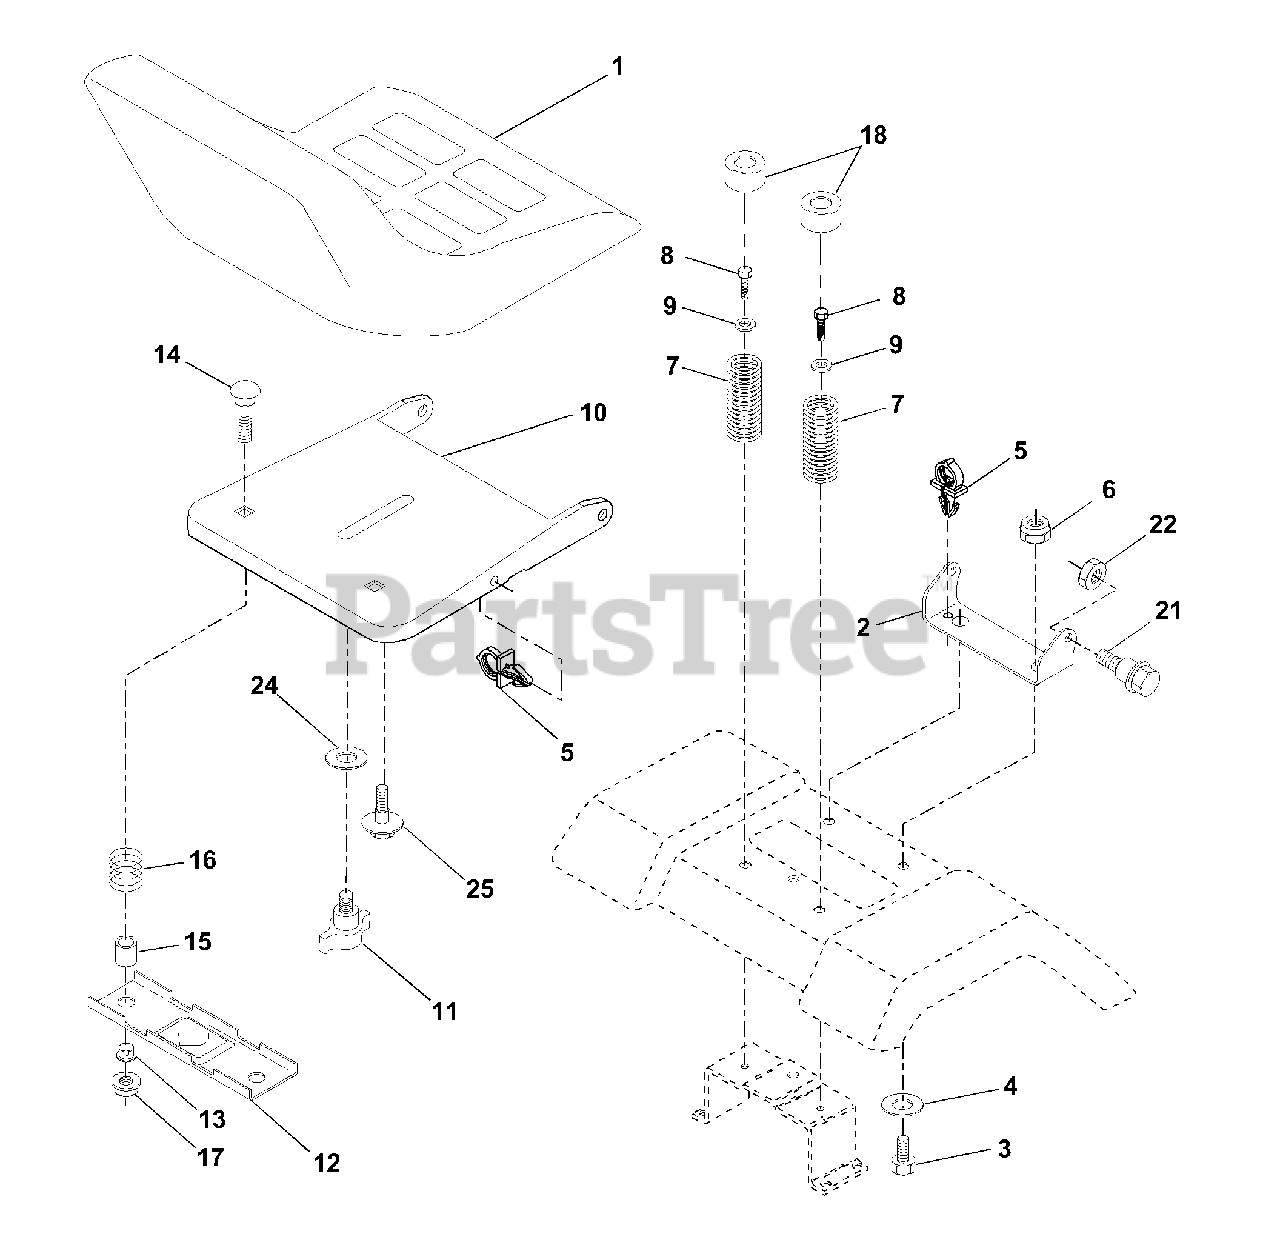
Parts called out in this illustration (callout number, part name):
1	Seat
2	Bracket Pivot Seat 8 720
3	Bolt Fin Hex 3/8-16unc X 1
4	Washer 13/32 X 1 X 10 Ga
5	Clip Push-In
6	Nut Hex w/Ins. 3/8-16 Unc
7	Spring Seat Cprsn 2 250 Blk Zi
8	Screw Thdrol 3/8-16 X 1-1/2
9	Washer 13/32 X 1 X 14 Ga.
10	Pan Seat
11	Knob Seat Adj Wingnut
12	Bracket Mounting Switch
13	Bushing Snap Blk Nyl 50 Id
14	Bolt Rdhd Sqnk 1/4-20x1-1/2
15	Spacer Split 28x 96 Yel Zinc
16	Spring Cprsn 1 27 Blk Pnt
17	Nut Lock 1/4 Lge Flg Gr 5 Zinc
18	Cap Spring Seat
21	Bolt Shoulder 5/16-18 Unc
22	Nut Hex Lock W/Ins 5/16-18
24	Washer 17/32 X 1-3/16 X 12 Ga.
25	Bolt Shoulder 5/16-18 X 62
